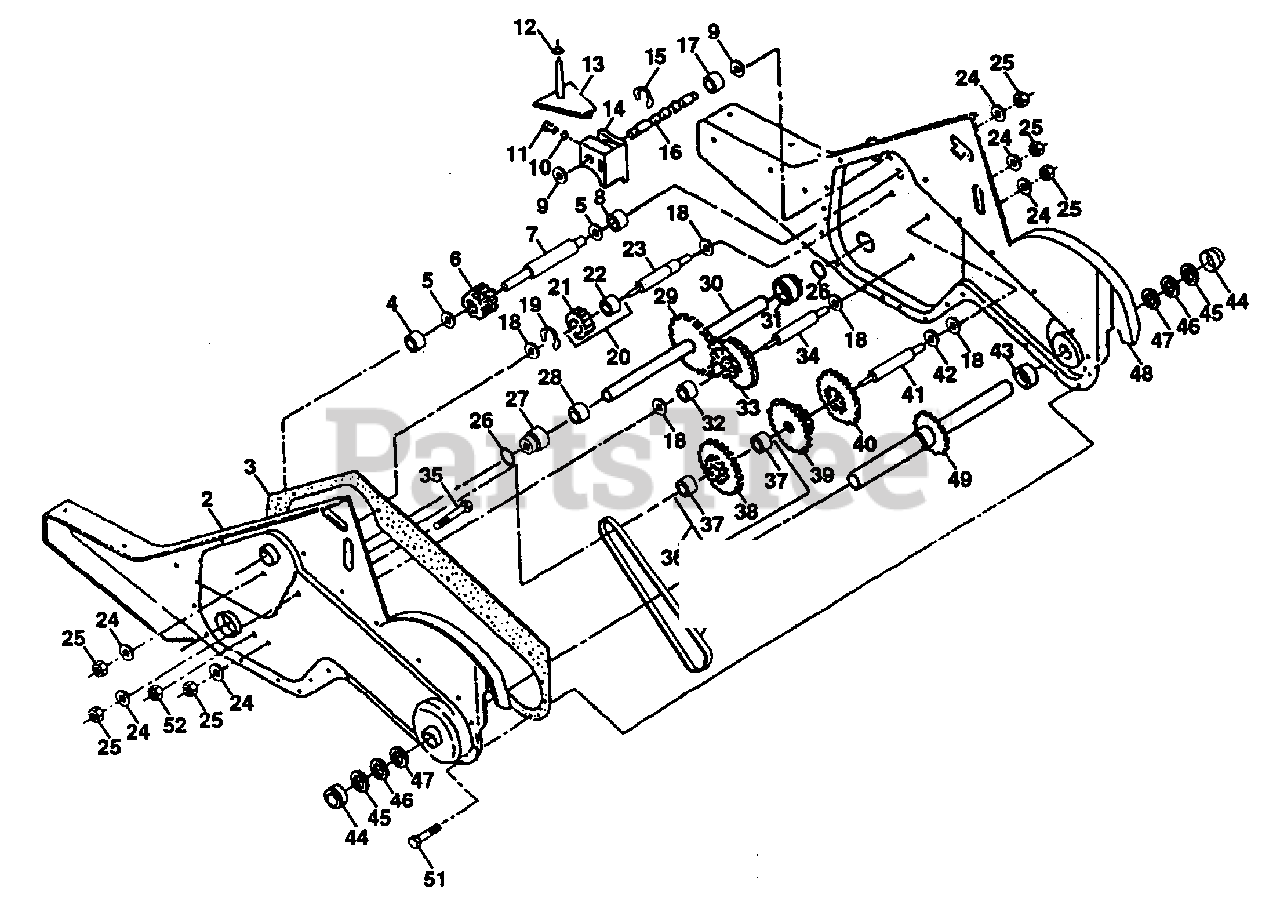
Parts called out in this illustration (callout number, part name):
1	Transmission Assembly (Includes Key Nos. 2-52) (AYP part number)
2	Gearcase, L.H. w/Bearing (AYP part number)
3	Gasket, Gearcase (AYP part number)
4	Bearing, Needle (AYP part number)
5	Washer, Thrust 5/8 x 1.10 x 1/32 (AYP part number)
6	Pinion, Input (AYP part number)
7	Shaft, Input (AYP part number)
8	Bearing, Needle (AYP part number)
9	Washer, Seal (AYP part number)
10	Ball, Steel (AYP part number)
11	Spring, Shift, Fork (AYP part number)
12	O-Ring (AYP part number)
13	Arm,. Shift (AYP part number)
14	Fork, Shift
15	Ring, Klip (AYP part number)
16	Shaft, Shift (AYP part number)
17	Spacer, Split (AYP part number)
18	Washer (AYP part number)
19	Ring, Klip (AYP part number)
20	Gear, Assembly, Reverse Idler (Includes Key Nos. 21 and 22)
21	Gear, Reverse Idler (AYP part number)
22	Bearing, Needle (AYP part number)
23	Shaft, Reverse Idler (AYP part number)
24	Washer, Lock 7/16 (AYP part number)
25	Nut, Hex 7/16-20 (AYP part number)
26	O-Ring (AYP part number)
27	Bearing, Shaft, Ground Drive (AYP part number)
28	Spacer 0.765 x 1.125 x 1.23 (AYP part number)
29	Chain #35-50 Pitch (AYP part number)
30	Ground Shaft Assembly (AYP part number)
31	Bearing, Shaft, Ground Drive (AYP part number)
32	Spacer 0.70 x 1.00 x 1.150 (AYP part number)
33	Sprocket and Gear Assembly (AYP part number)
34	Shaft, Reduction (2nd) (AYP part number)
35	Screw, Whiz, Lock 5/16-18 x 3-1/2 (AYP part number)
36	Sprocket Assembly w/Bearing (Includes Key Nos. 37 and 38) (AYP part number)
37	Bearing, Needle (AYP part number)
38	Sprocket, Tine (AYP part number)
39	Gear, Cluster, Red 1st & 2nd (AYP part number)
40	Gear, Reverse (AYP part number)
41	Shaft, Reduction (1st) (AYP part number)
42	Washer, Thrust (AYP part number)
43	Spacer 1.01 x 1.75 x 0.760
44	Cup, Formed (AYP part number)
45	Ring, Spiral (AYP part number)
46	Seal, Ring, Rubber (AYP part number)
47	Seal, Oil (AYP part number)
48	Gearcase, R.H. w/Bearing (AYP part number)
49	Shaft, Tine (AYP part number)
50	Chain, Roller #50-50 Pitch (AYP part number)
51	Screw 1/4-20 x 1/2 (AYP part number)
52	Nut, Hex 5/16-18 (AYP part number)
